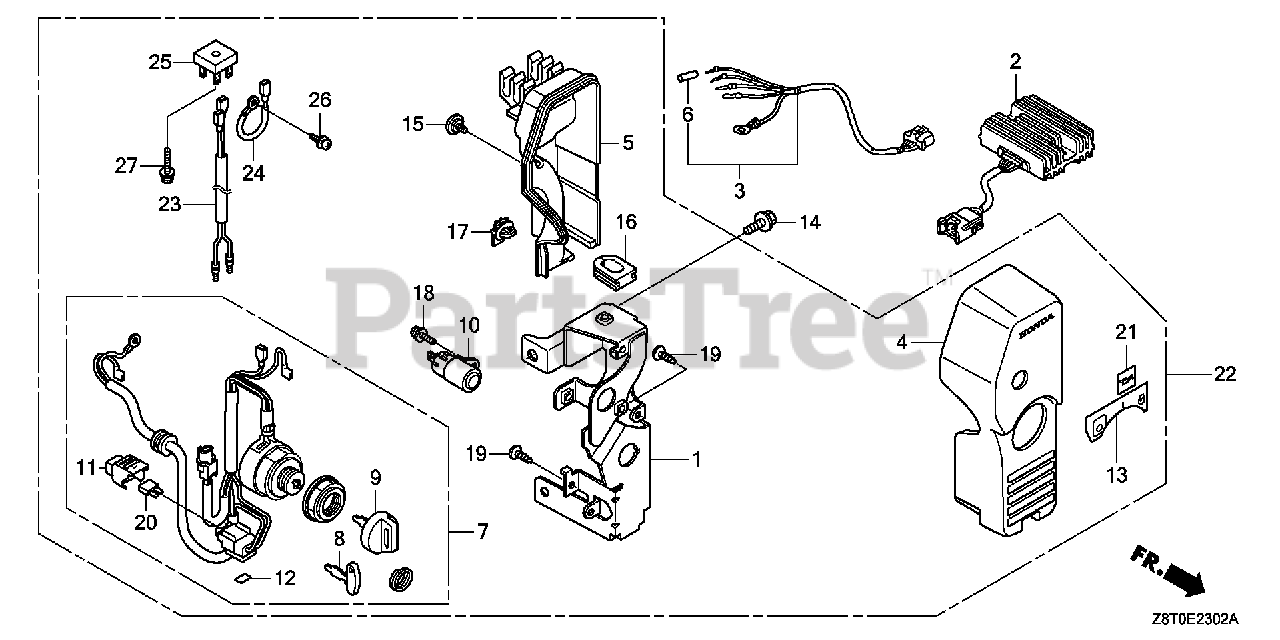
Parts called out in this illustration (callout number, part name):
1	BRACKET, SWITCH BOX
4	PANEL, CONTROL
5	COVER, CONTROL
7	SWITCH ASSY., COMBINATION (IND)
9	KEY ASSY., COMBINATION SWITCH (BLACK)
10	INDICATOR ASSY.
11	COVER ASSY., FUSE
12	LABEL, FUSE (30A)
13	MARK, ENGINE SWITCH
14	BOLT, FLANGE (6X12) (CT200)
15	SCREW, SPECIAL (6X8)
16	GROMMET, CONTROL BOX
17	CLIP, CONNECTOR (BLACK)
18	SCREW-WASHER (4X10)
19	SCREW, TAPPING (4X14) (PO)
20	FUSE, MINI (30A)
21	MARK, OIL CAUTION
22	BOX ASSY., CONTROL
23	WIRE, CHARGE COIL
24	WIRE, GROUND
26	SCREW-WASHER (4X8)
27	SCREW-WASHER (4X20)
